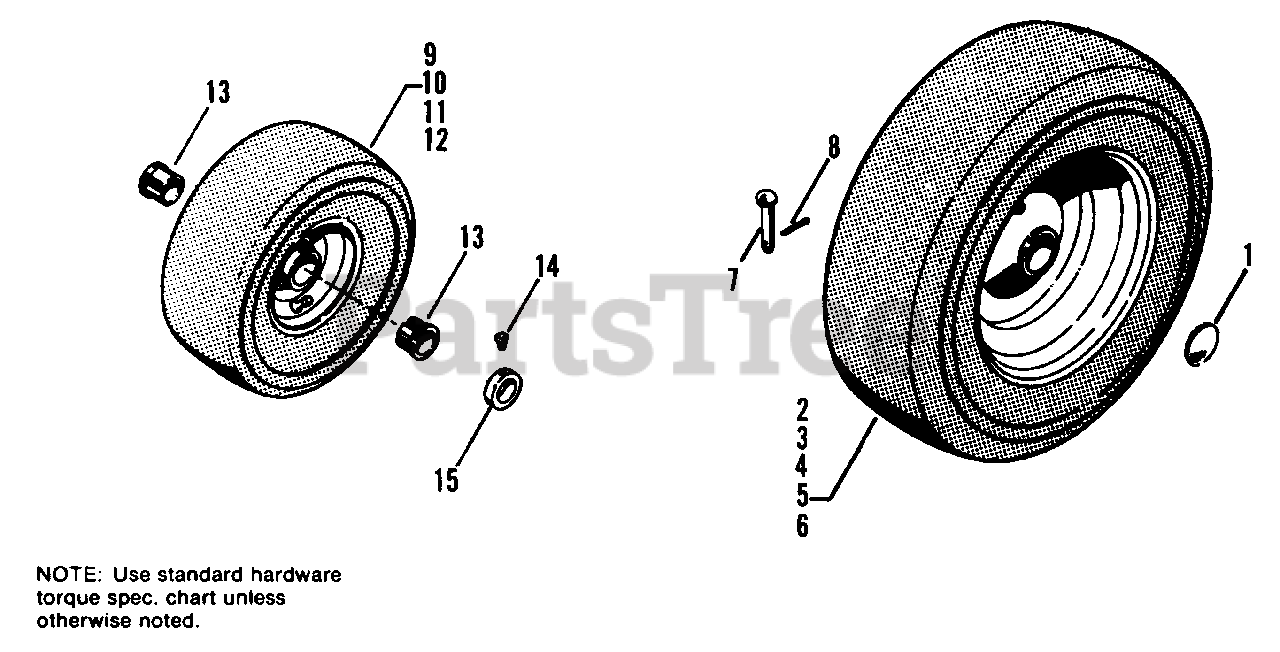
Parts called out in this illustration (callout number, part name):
1	BUTTON, Plug
2	WHEEL & TIRE ASSY., Rear
3	WHEEL ASSY.
4	TIRE, Tubeless
6	STEM, Valve, Cap
7	PIN
8	PIN, Cotter, 1/8 x 3/4
9	WHEEL & TIRE ASSY., Front
13	BEARING, Relief
14	SETSCREW, 5/16-18 x 5/16
15	COLLAR, Set
